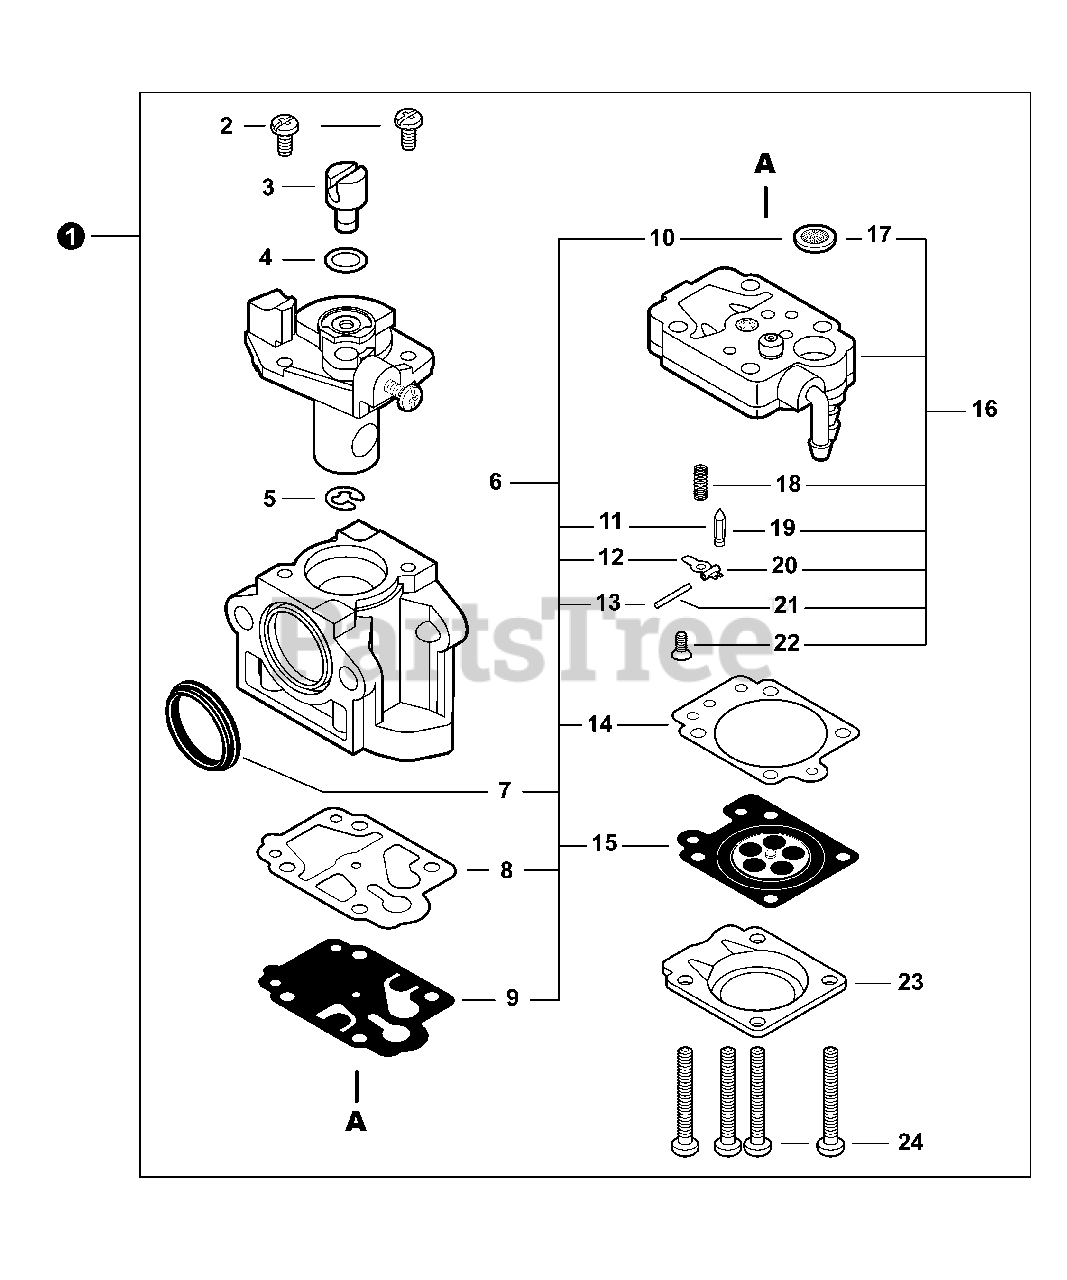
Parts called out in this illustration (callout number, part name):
1	CARBURETOR - WYK-406
6	REPAIR KIT, CARBURETOR
7	RING, PACKING
8	GASKET, PUMP
9	DIAPHRAGM, PUMP
10	SCREEN, FUEL INLET
11	VALVE, INLET NEEDLE
12	LEVER, METERING
13	PIN, METERING LEVER
14	GASKET, METERING DIAPHRAGM
15	DIAPHRAGM, METERING
16	BODY ASSY, PUMP
17	SCREEN, FUEL INLET
18	SPRING, METERING LEVER
19	VALVE, INLET NEEDLE
20	LEVER, METERING
21	PIN, METERING LEVER
22	SCREW
23	COVER, METERING DIAPHRAGM
